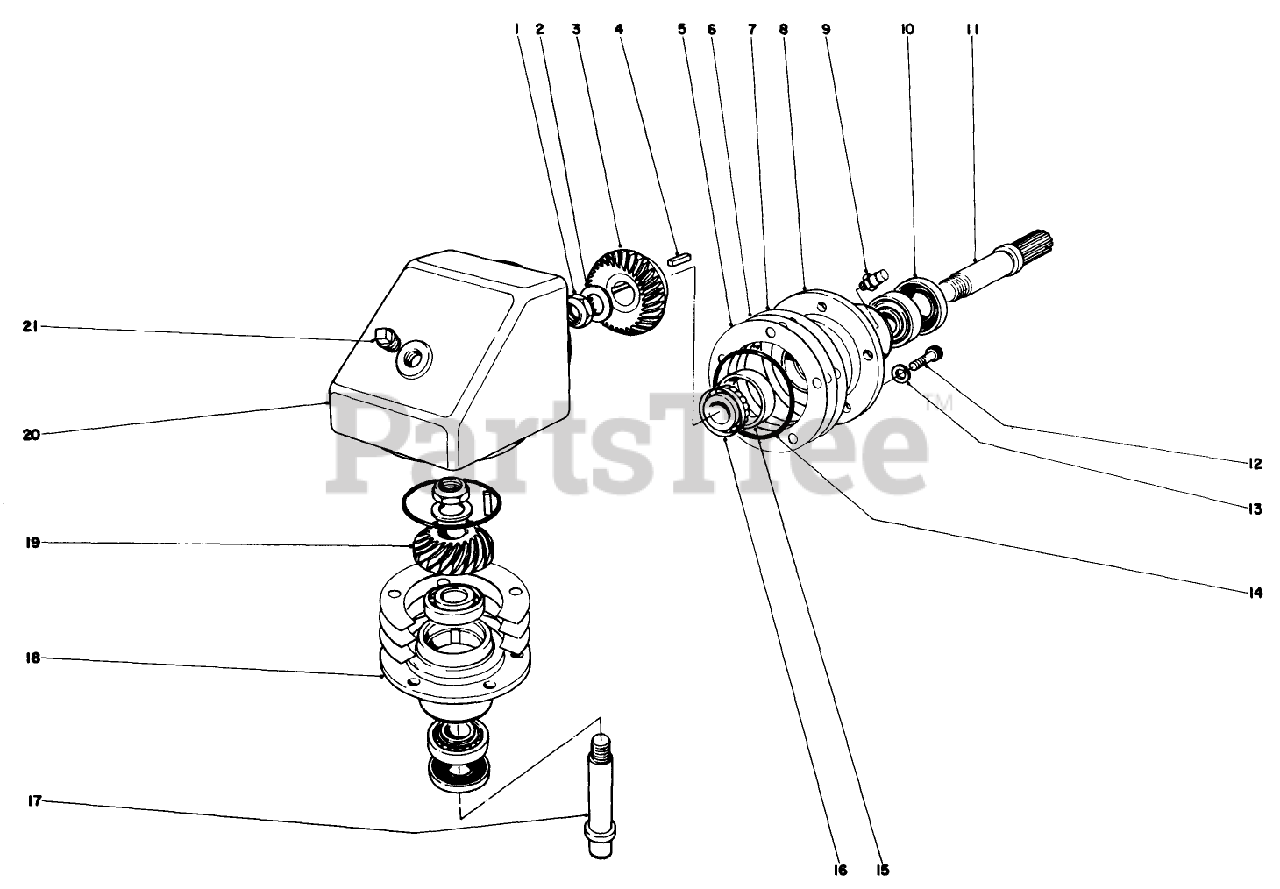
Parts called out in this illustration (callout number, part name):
1	NUT-LOCK, NI
2	THRUST WASHER
4	KEY-SQUARE
5	.002 SHIM (RED)
6	.005 SHIM (BLUE)
7	.015 SHIM (PINK)
8	INPUT BRG HSG
10	OIL SEAL
11	INPUT SHAFT
12	SCREW-HSH
13	WASHER-LOCK
14	O-RING
15	BEARING-CUP
16	CONE-BEARING
17	OUTPUT SHAFT
18	OUTPUT BRG HSG
19	PINION
20	GEAR BOX
21	3/8-18 SQ HD PLUG/MAG
